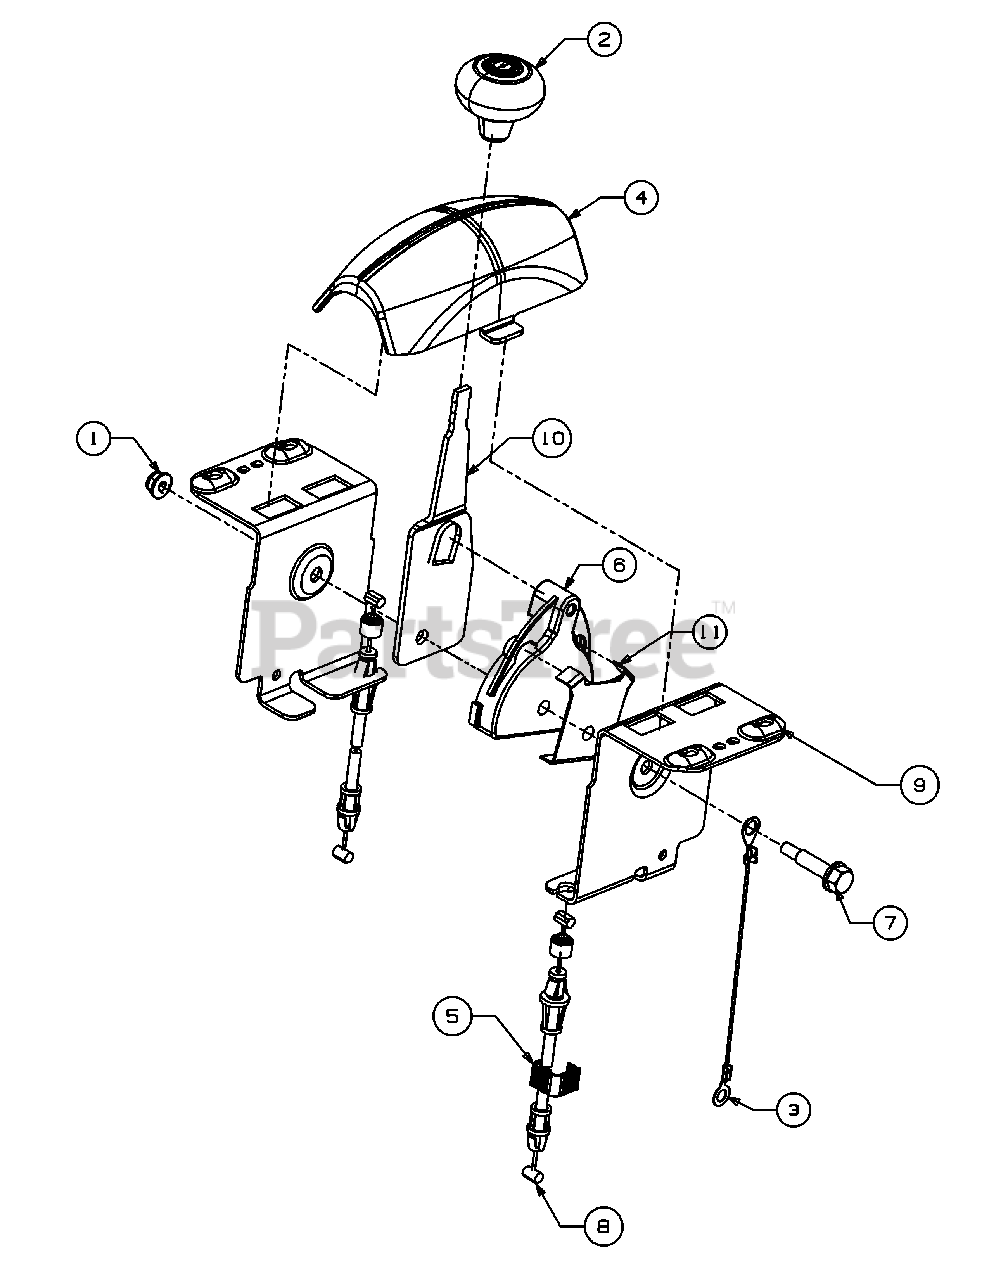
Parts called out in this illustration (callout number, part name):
1	Flange Lock Nut, 1/4-20
2	Shift Knob
3	Ground Wire
4	Tilt Cover
5	Cable Clip
6	Cable Guide
7	Screw, Shoulder, .31 x .995:1/4-20
8	Pitch Control Cable
9	Mounting Bracket
10	Control Lever
11	Grounding Bracket
